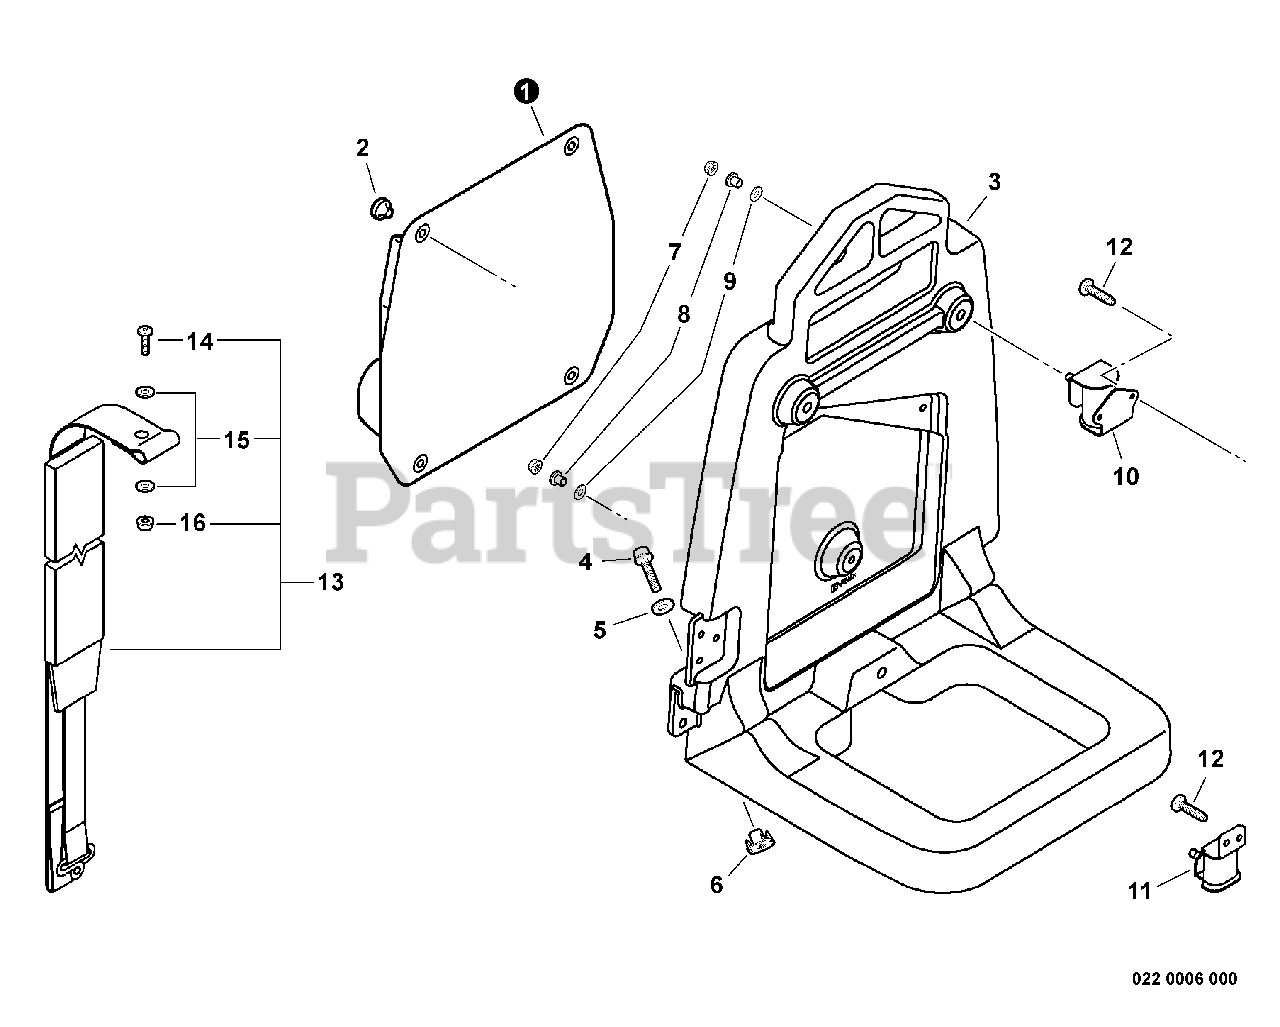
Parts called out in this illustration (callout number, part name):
1	CUSHION, BACKPACK
3	BACKPACK FRAME ASSY
4	SCREW - 6X25
5	WASHER - 6
7	LOCKNUT - 5
9	WASHER - RUBBER
11	CUSHION
12	SCREW - 5X16 -- TAPPING
13	BACKPACK STRAP ASSY
14	SCREW - 5X14
16	NUT - 5 -- FLANGE
